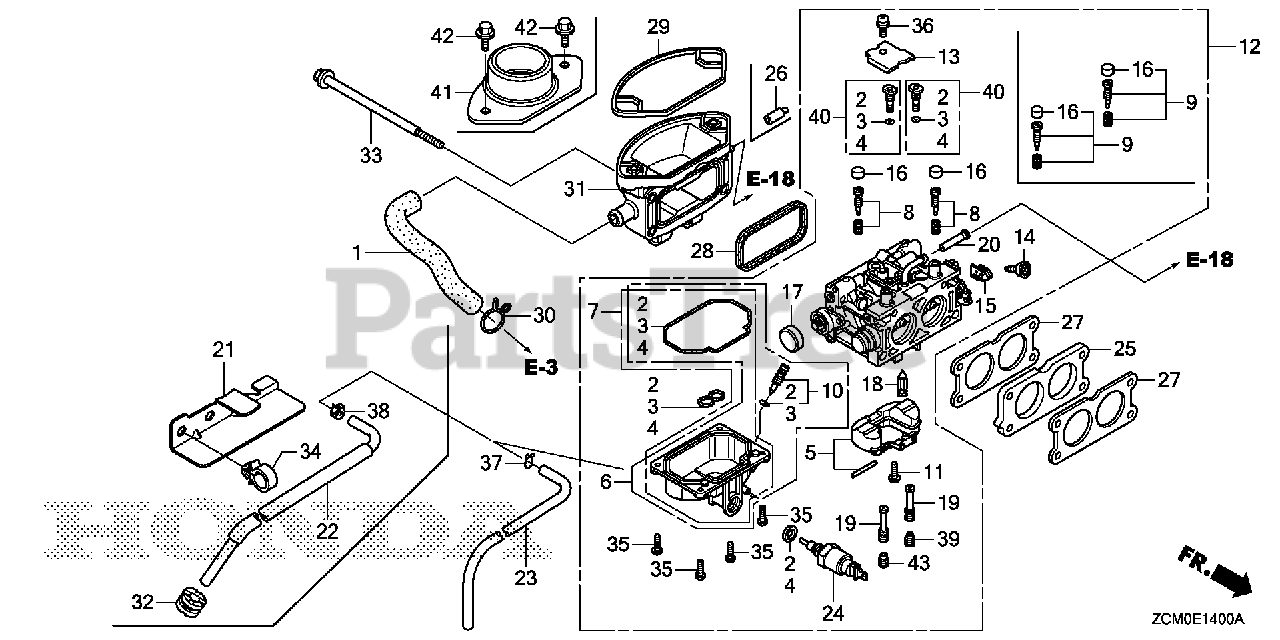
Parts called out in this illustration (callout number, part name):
1	TUBE, BREATHER
2	GASKET SET
6	CHAMBER SET, FLOAT
10	SCREW SET, DRAIN (ADVENTURE GREEN) (CARBURETOR NO.)
11	SCREW, FLOAT
12	CARBURETOR ASSY. (BK05T A)
14	SCREW, THROTTLE STOP
15	ARM, THROTTLE LINKAGE
16	CAP, ADJUSTING SCREW (CARBURETOR NO.)
17	CAP, CHOKE LEVER DUST
18	VALVE, FLOAT
19	NOZZLE, MAIN
20	SCREEN, FUEL STRAINER
23	TUBE, DRAIN
24	VALVE ASSY., SOLENOID
25	INSULATOR, CARBURETOR
27	GASKET, CARBURETOR
28	GASKET, AIR CLEANER
29	SEAL, AIR CLEANER HOUSING
30	CLIP, BREATHER TUBE
31	ELBOW, AIR CLEANER
33	BOLT, FLANGE (6X106)
35	SCREW, PAN (4X12)
36	SCREW-WASHER (5X10)
37	CLIP, TUBE (B8)
39	JET, MAIN (#105) Use from Engine SN BE87H A.
39	JET, MAIN (#110) (CARBURETOR NO.)
39	JET, MAIN (#115)
40	JET SET, PILOT (#45)
41	JOINT, CONNECTING TUBE
42	BOLT, FLANGE (6X12) Use up to Engine SN 1543277.
43	JET, MAIN (#108) (CARBURETOR NO.)
43	JET, MAIN (#112)
43	JET, MAIN (#118)
